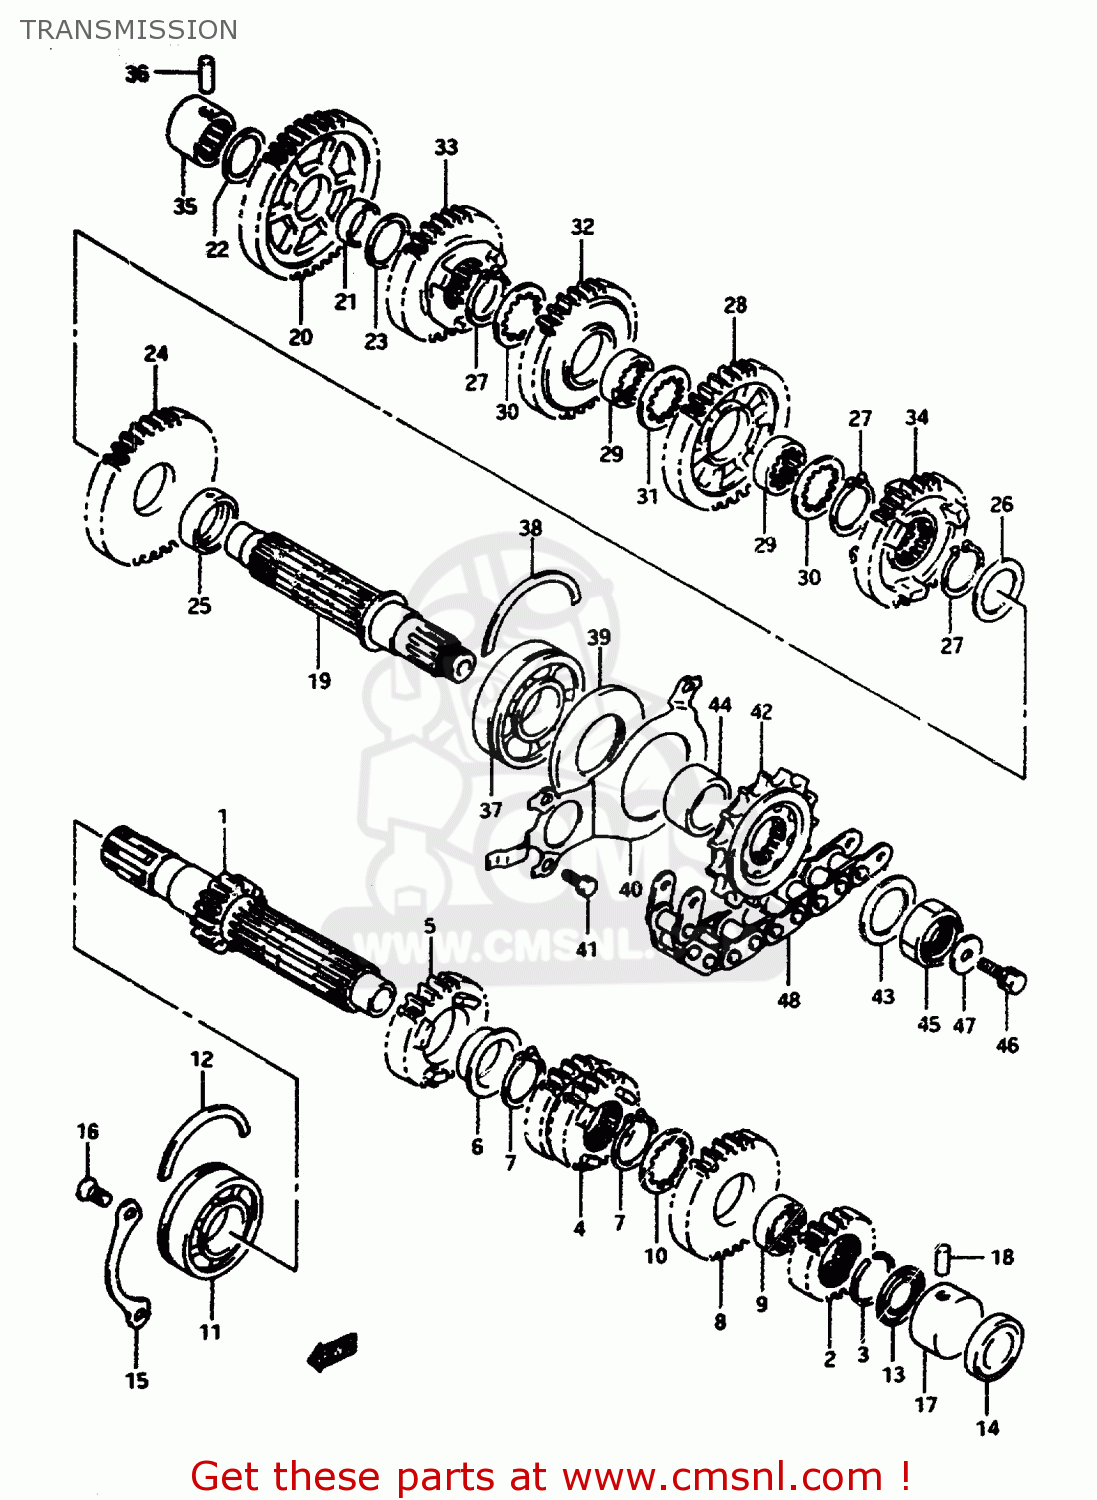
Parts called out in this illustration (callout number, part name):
1	SHAFT,COUNTER
2	GEAR,SECOND DRIVE
3	CIRCLIP
4	GEAR,THIRD & FOURTH DRIVE
5	GEAR,FIFTH DRIVE
6	BUSH(28X32X2)
7	CIRCLIP
8	GEAR,SIXTH DRIVE
9	BUSHING,SIXTH DRIVE GEAR
10	WASHER,LOCK
11	BEARING(25X62X17)
12	C-RING
13	SEAL,OIL(20X31.2X2.7)
14	CAP,COUNTER SHAFT,L
15	RETAINER,CNTR SHAFT BEARING
16	SCREW
17	BEARING(20X34X17.5)
18	PIN
19	SHAFT,DRIVE
20	GEAR,1ST DRIVEN
21	BUSH(22X26X9)
22	WASHER
23	WASHER
24	GEAR,2ND DRIVEN
25	BUSH(28X32X9.5)
26	SHIM(28X38X1)
27	CIRCLIP
28	GEAR,3RD DRIVEN(NT:33)
29	BUSH,3RD DRIVEN GEAR
30	WASHER,LOCK
31	WASHER,LOCK
32	GEAR,FOURTH DRIVEN
33	GEAR,5TH DRIVEN(NT:29)
34	GEAR,6TH DRIVEN
35	BEARING(20X34X20)
36	PIN
37	BEARING(28X70X18)
38	C RING
39	SEAL,OIL(34.8X70X6)
40	RETAINER,DRIVE SHAFT OIL SEAL
41	BOLT
42	SPROCKET,ENGINE(14T)
43	WASHER,THRUST
44	SPACER(25X36X17.7)
45	NUT
46	BOLT
47	WASHER
48	CHAIN ASSEMBLY,DRIVE 108LE
